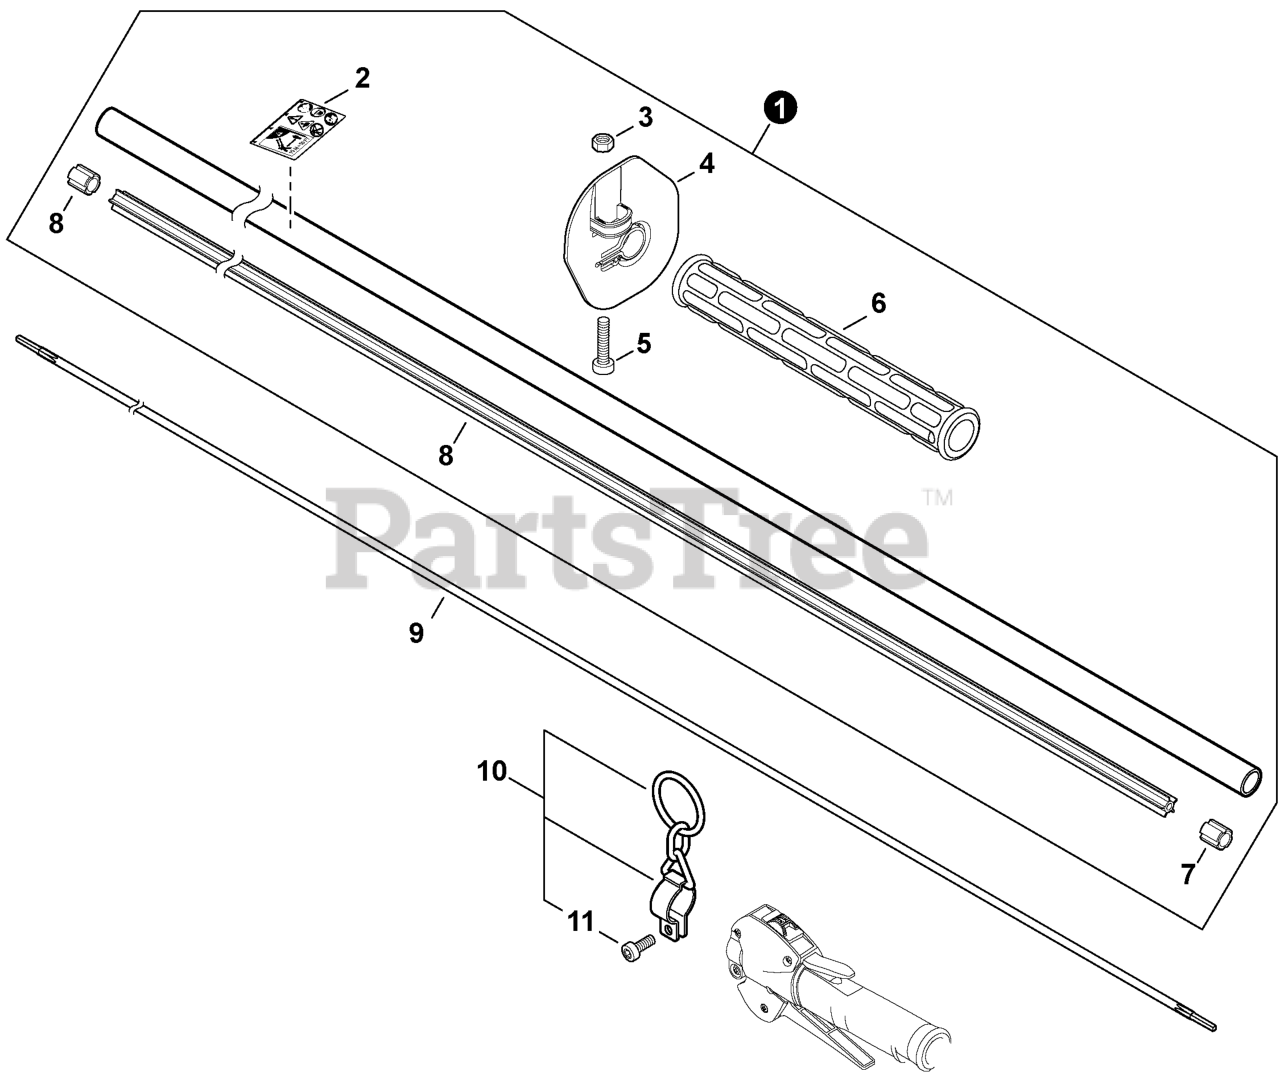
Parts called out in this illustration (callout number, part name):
1	MAIN PIPE ASSY
2	LABEL - CAUTION
4	GUARD, HAND
5	BOLT, TORX 5x20
6	GRIP, FRONT
8	LINER, FLEXIBLE 21.6x1420
9	DRIVESHAFT - FLEXIBLE
10	HANGER SET, HARNESS
11	BOLT, TORX 5x12
